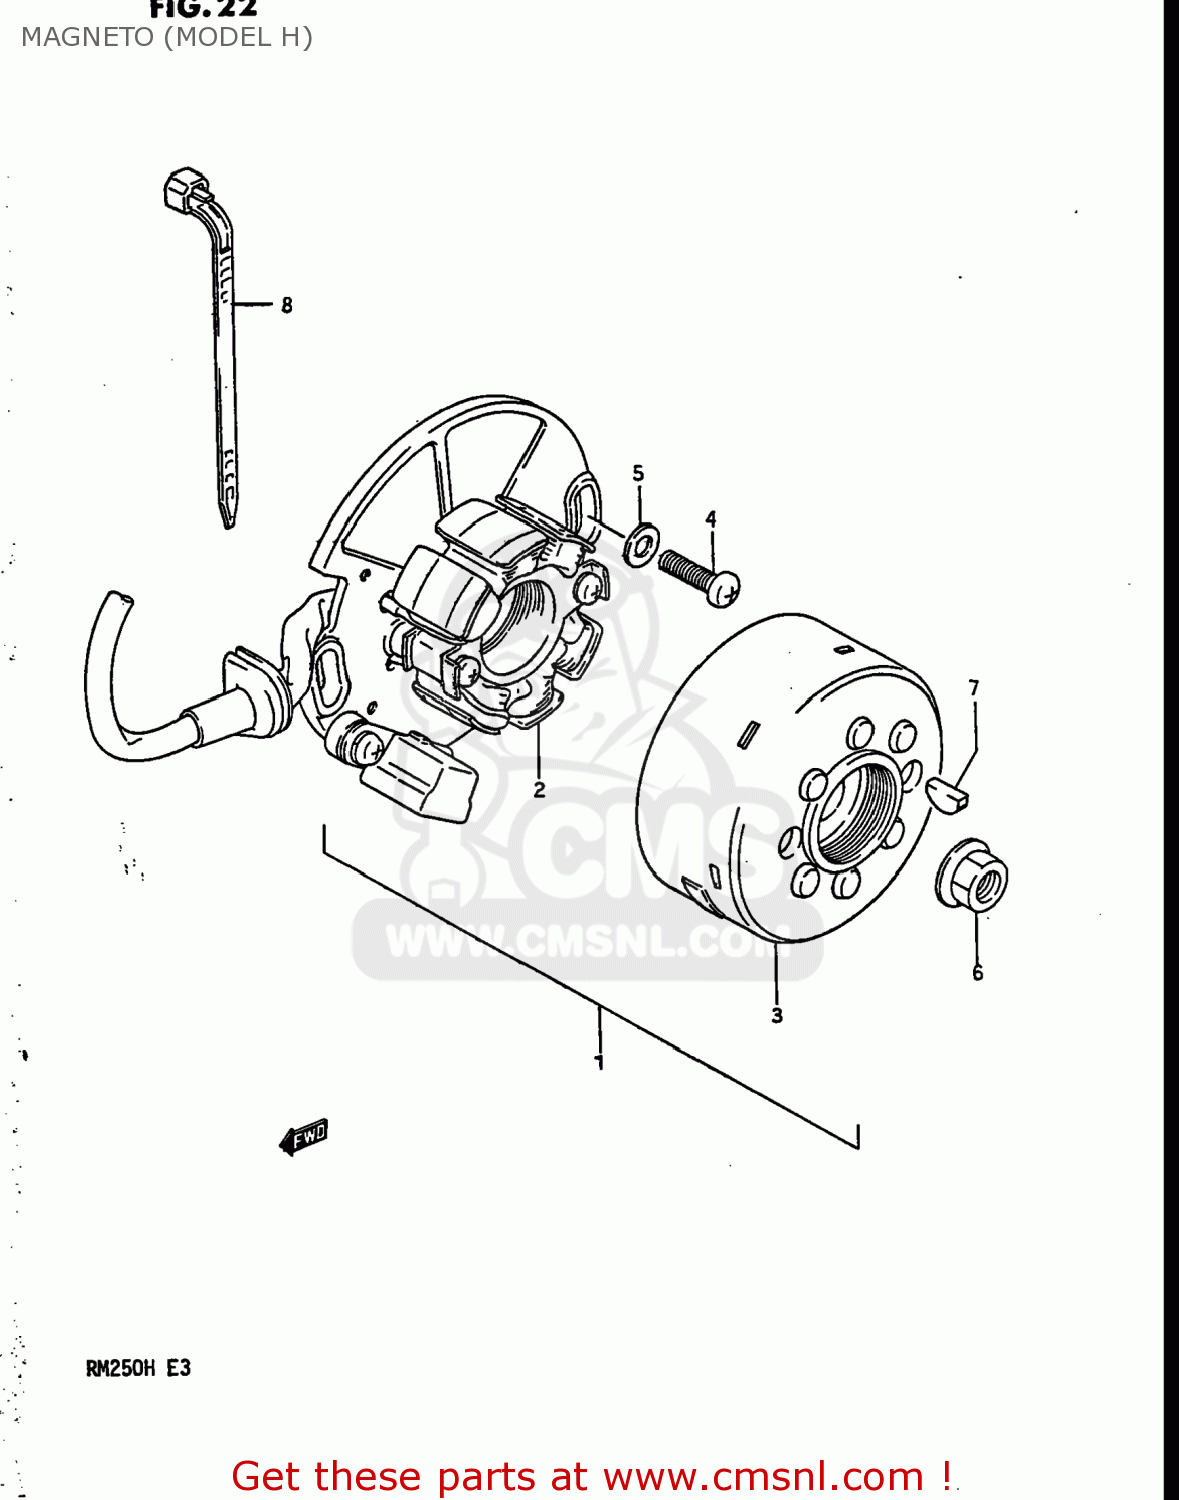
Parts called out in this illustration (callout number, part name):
1	MAGNETO ASSEMBLY
2	STATOR ASSEMBLY
3	ROTOR
4	SCREW 6X30
5	WASHER
6	NUT
7	KEY 4MM
8	CLAMP(L:125)
